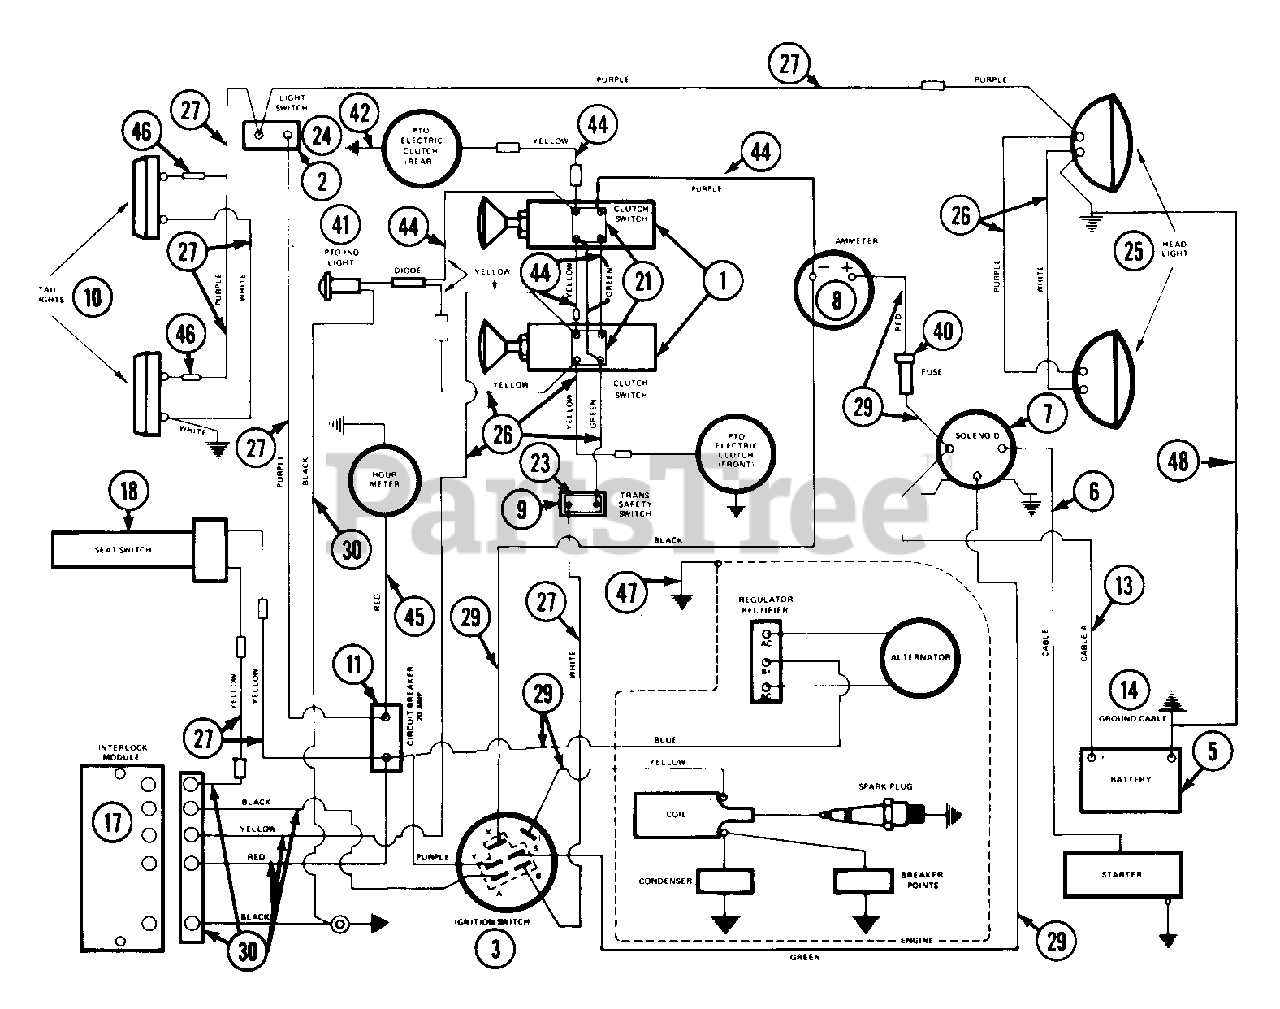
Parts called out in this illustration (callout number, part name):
1	CLUTCH SWITCH
2	LIGHT SWITCH
3	SWITCH & KEY SET ASSEMBLY
5	BATTERY
6	GROUND CABLE
7	SOLENOID
8	AMMETER
9	SAFETY SWITCH
10	TAIL LIGHT
11	CIRCUIT BREAKER
14	GROUND CABLE
17	INTERLOCK MODULE
18	SWITCH SEAT
20	CONNECTOR HOUSING
21	CONNECTOR
23	CONNECTOR
24	CONNECTOR
25	HEAD LIGHT
26	HEADLIGHT & CLUTCH HARNESS
27	TAIL LIGHT HARNESS ASSEMBLY
29	DASH HARNESS
30	INTERLOCK MODULE HARNESS
40	STD 30 A SAE FUSE
41	PTO INDICATOR LIGHT
41	SPEED NUT
42	GROUND WIRE
44	CLUTCH HARNESS
45	WIRING HARNESS
46	MALE DISCONNECT ADAPTER
47	GROUND CABLE .31X22.00X.31
48	WIRE - GROUND
48	WSHR-LK .312X.097 PL HVY
48	NUT-JAM .312-24 PL
48	WSHR-LK 10X.047 MED PL
48	NUT 10-32 PL
